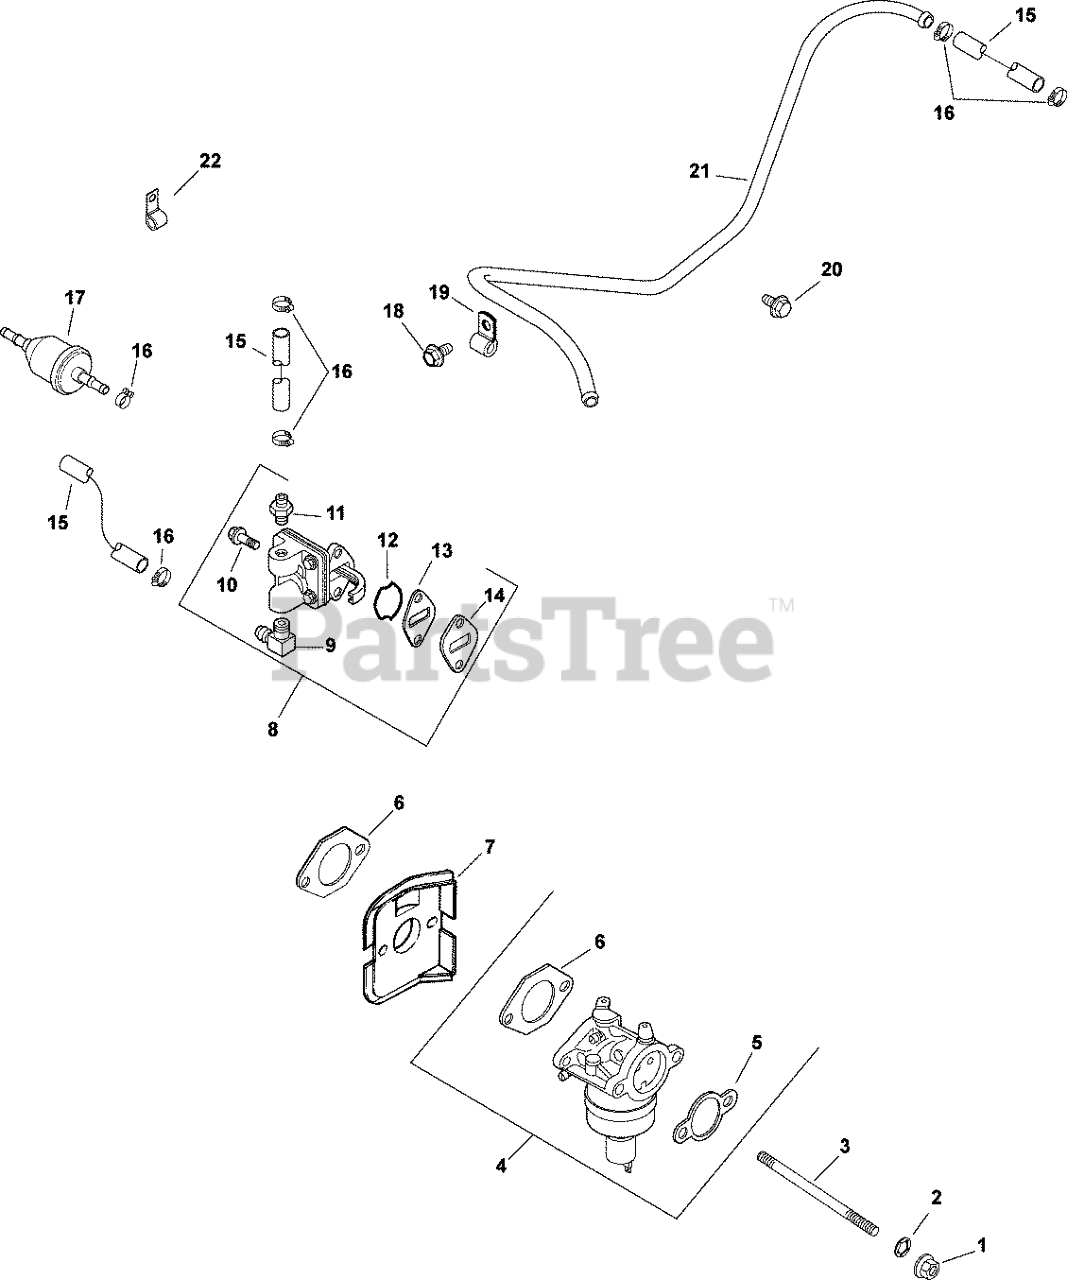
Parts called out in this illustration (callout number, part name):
1	NUT, FLG M6X1.0
2	WASHER, INT TOOTH LOCK 1/4"
3	STUD,M6X1.0X116
4	KIT, CARB W/GASKETS - USE 12 853 93-S
5	GASKET, AIR CLEANER BASE
6	GASKET, CARBURETOR
7	DEFLECTOR, HEAT
8	KIT, FUEL PUMP
9	CONNECTOR, 90 DEG. HOSE
10	SCREW, LBD SKT M6x1.0x20-(#25086403S)
11	KIT, STRAIGHT FITTING
12	O-RING, FUEL PUMP
13	GASKET, FUEL PUMP
14	SPACER, FUEL PUMP
15	HOSE,LW PERM.FUEL 24.00"-USE 25 111 81-S
16	CLAMP, HOSE (KM)-USE 25 237 31-S
17	FILTR,FUEL 75 MICRON (GRAVTY FEED)
18	SCREW, THRD FRM M5X0.8X10
19	CLIP, TUBE & WIRING (KM)
20	SCREW, FLG THD FRM M5X.8X10
21	LINE, FUEL
22	CLIP, CABLE
